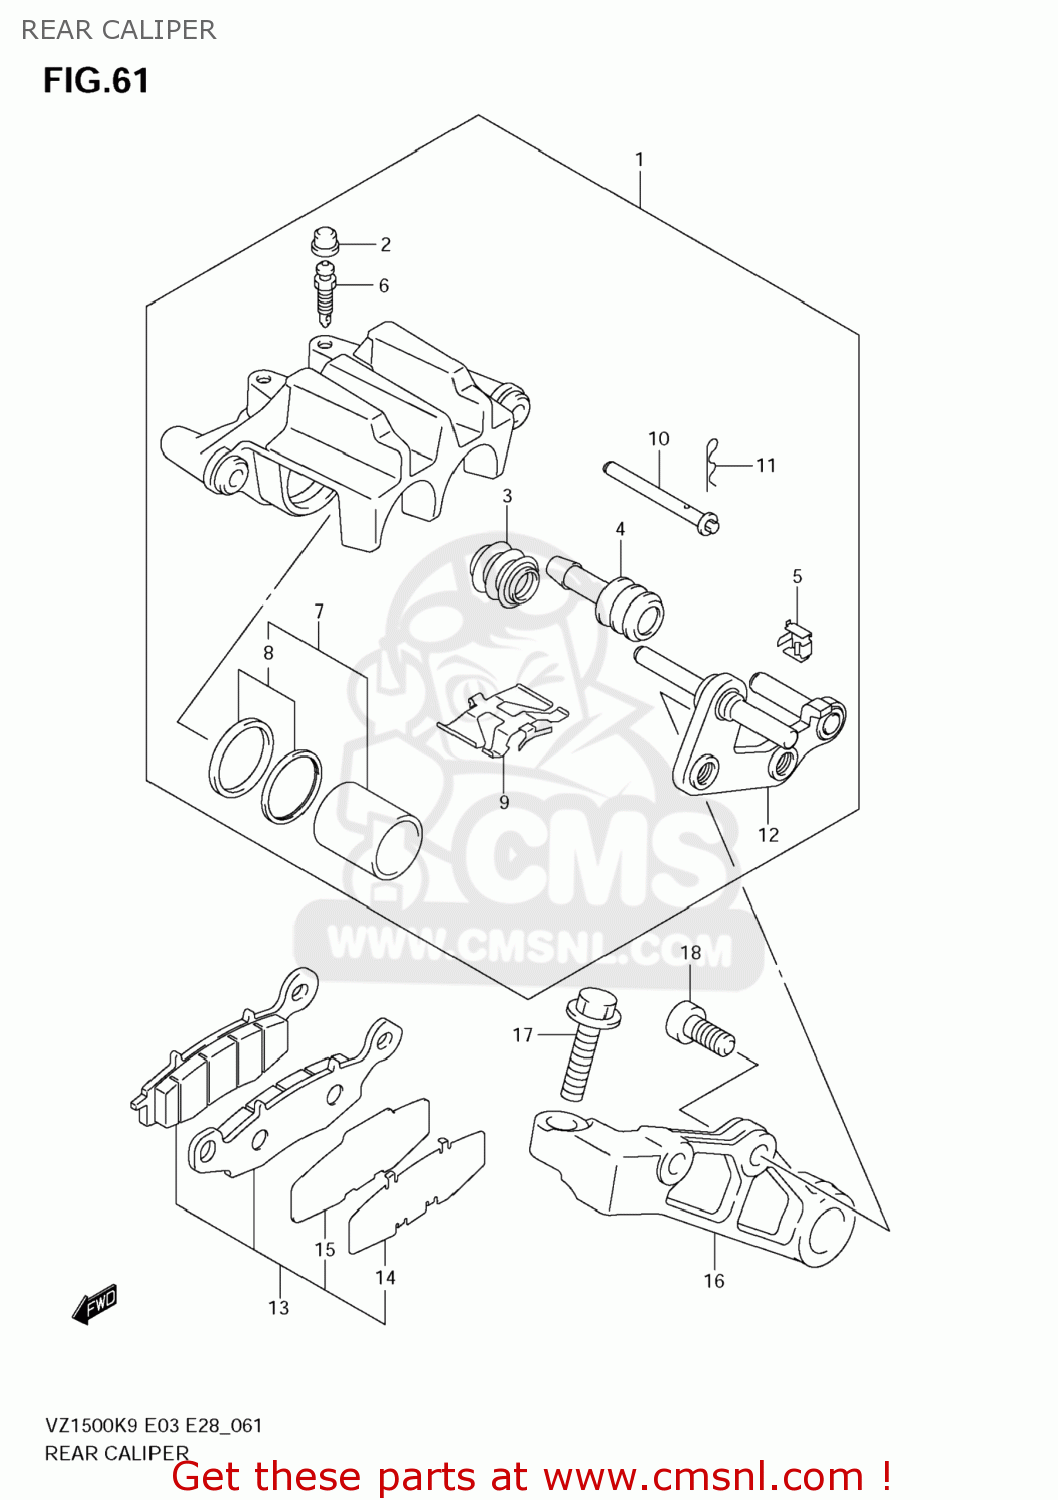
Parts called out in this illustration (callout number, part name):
1	CALIPER ASSY,RR
2	CAP,BLEEDER PLUG
3	BOOT,AXLE
4	INSULATOR,AXLE
5	GUIDE,PAD
6	BLEEDER
7	PISTON SET
8	SEAL SET,PISTON
9	SPRING,PAD
10	PIN,PAD
11	CLIP,PAD PIN
12	CARRIER,CALIPER
13	PAD & SHIM SET (NAS)
14	SHIM,PAD NO.2
15	INSULATOR NO.2
16	BRACKET,RR CALIPER
17	BOLT(12X40)
18	BOLT(10X20)
